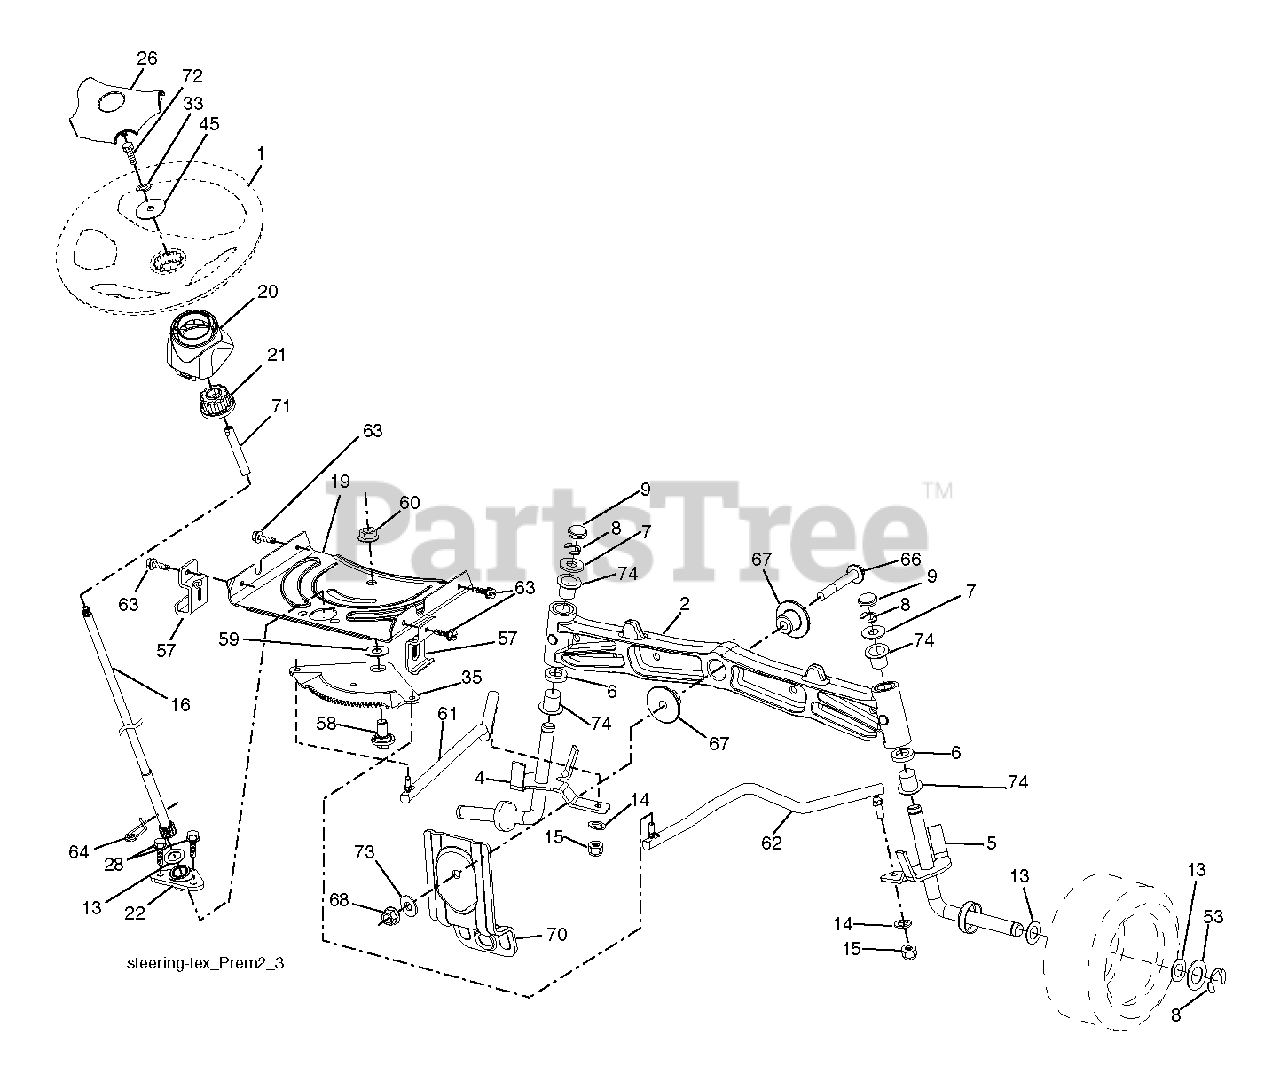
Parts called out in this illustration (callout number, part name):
1	WHEEL.STEERING.PREM.2.BLK
2	AXLE.HALF.ASM.WELDED
4	SPINDLE.WELDED.LH.15"TEX
5	SPINDLE.WELDED.RH.15"T
8	RING CLIP
9	CAP.SPINDLE
14	WASHER, LOCK 3/8
15	NUT CROWNLOCK 3/8-24
16	SHAFT STEERING
19	PLATE.STEER.DDL.NLT/NG
20	BOOT STEERING BLACK
21	ADAPTER, WHEEL STNG..
22	BUSHING.ASM.STEERING.A
26	INSERT.CAP.STRG.WH.BLACK
28	SCREW, 3/8-16X3/4
33	LOCKWASHER
35	GEAR.SECTOR.PLATE.DDL.
45	WASHER.11/32
53	WASHER.HARDENED
57	BRACKET.UPSTOP.TEX
58	BOLT.SHOULDER.SECTOR.P
59	WASHER.THURST.SECTOR.S
60	NUT FLANGE LOCK 5/8-11
61	DRAGLINK.LH.BALLSTUD.D
62	DRAGLINK.RH.BALLSTUD.D
63	SCREW
64	RETAINER.CLIP.SPRING.S
66	BOLT HEX FGHD 7/16-14 X 3 SERR
67	BUSHING.PM.FRONT AXLE
68	NUT.LOCK.FLANGE.7/16
70	BRKT.DECK.SUSPENSION.F
71	SHAFT EXTENSION STEERING
72	BOLT YT
73	WASHER.1.5X.505X.118
74	BRNG T
